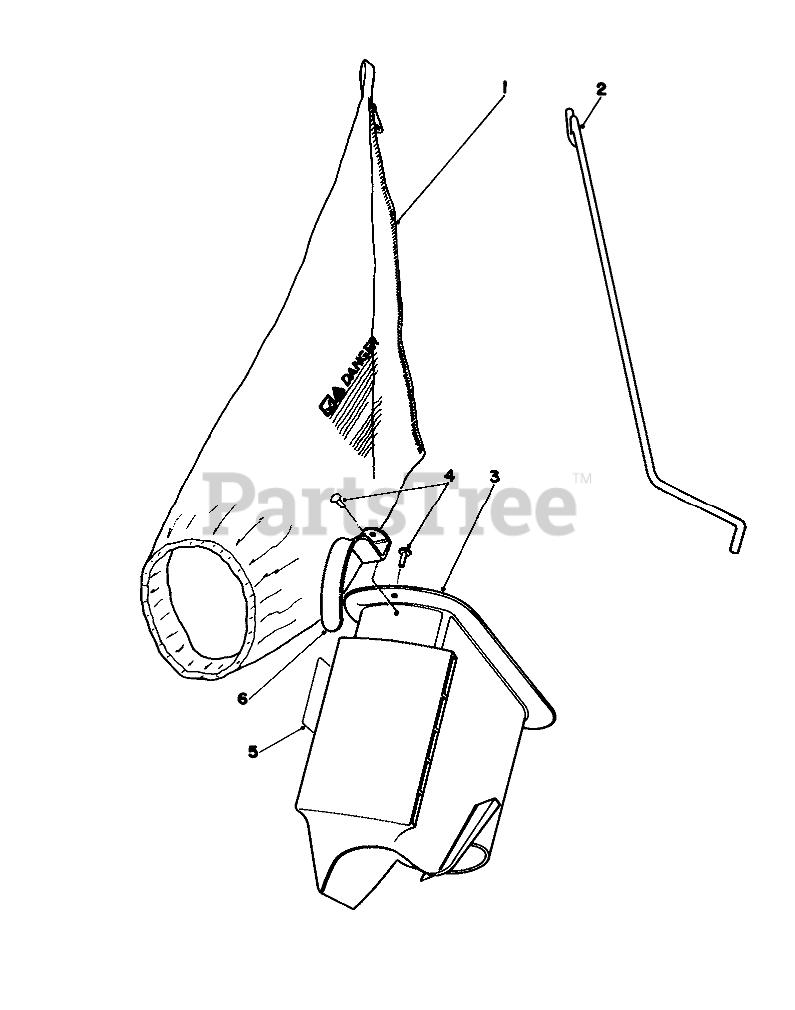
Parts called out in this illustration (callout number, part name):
1	BAG REPLACMNT44-0540
2	BAG ROD
3	Grass Chute (Incl. Ref. #4 & 6)
4	RIVET 3/16 X 7/16
5	BAG CHUTE DECAL
6	HANDLE-GRASS CHUTE
